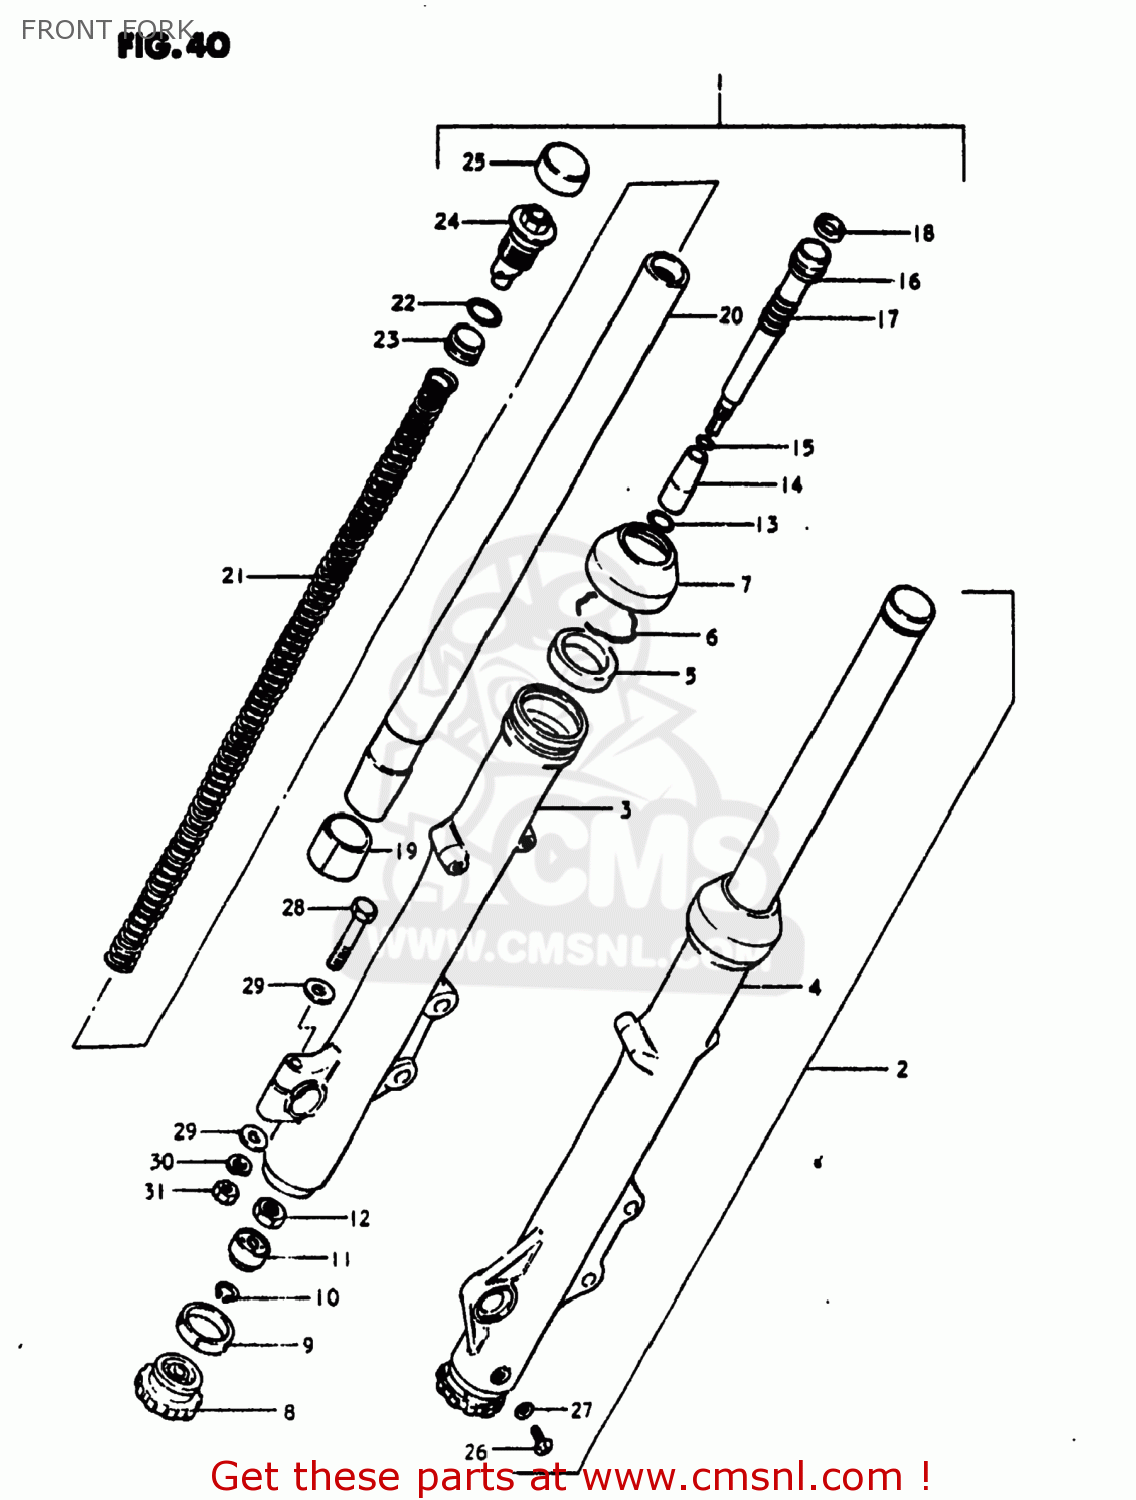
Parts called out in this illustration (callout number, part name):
3	OUTER TUBE, RH
4	OUTER TUBE, LH
5	OIL SEAL,FRONT FORK
6	RING,STOPPER
7	SEAL,DUST
8	HANDLE
9	RING
10	CIRCLIP
11	DETENT
12	NUT
13	O RING
14	PIECE, OIL LOCK
15	O RING
16	CYLINDER,FRONT FORK
17	SPRING,FORK REBOUND
18	RING,PISTON
19	PISTON
20	INNER TUBE
21	SPRING
22	O-RING
23	PISTON,FREE
24	CAP
25	CAP
26	SCREW
27	GASKET,DRAIN,PLUG (NAS)
28	BOLT 8X50
29	WASHER
30	WASHER,LOCK,8.
31	NUT
